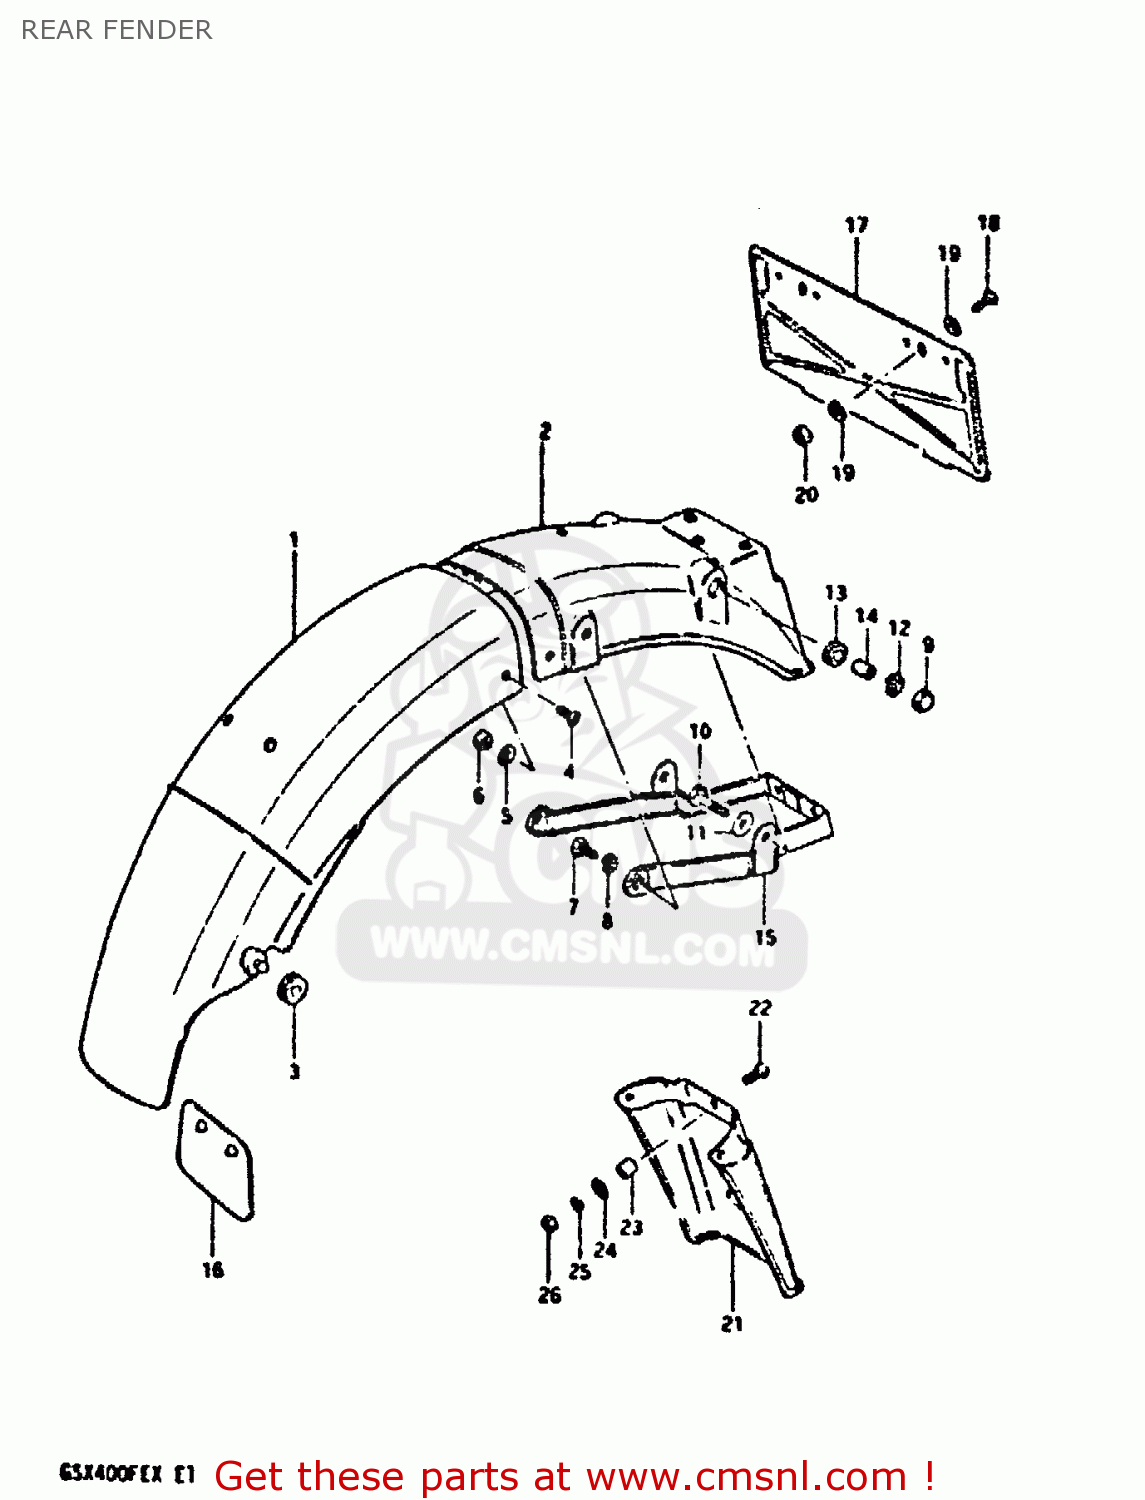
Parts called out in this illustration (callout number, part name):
1	BODY,RR FENDER FR
2	BODY, REAR FENDER REAR
3	CUSHION
4	SCREW
5	WASHER (5.5X16X1.2)
6	NUT
7	BOLT, UPPER
8	LOCK WASHER
9	NUT
10	BOLT
11	WASHER
12	LOCK WASHER
13	CUSHION
14	SPACER (8.2X12X7.5)
15	REINFORCEMENT, REAR FENDER
16	GUIDE,RR FENDER MUD
17	HOLDER,RR LICENSE PLATE
18	BOLT
19	WASHER
20	NUT
21	EXTENSION, REAR FENDER
22	SCREW (6X15)
25	LOCK WASHER
26	NUT
